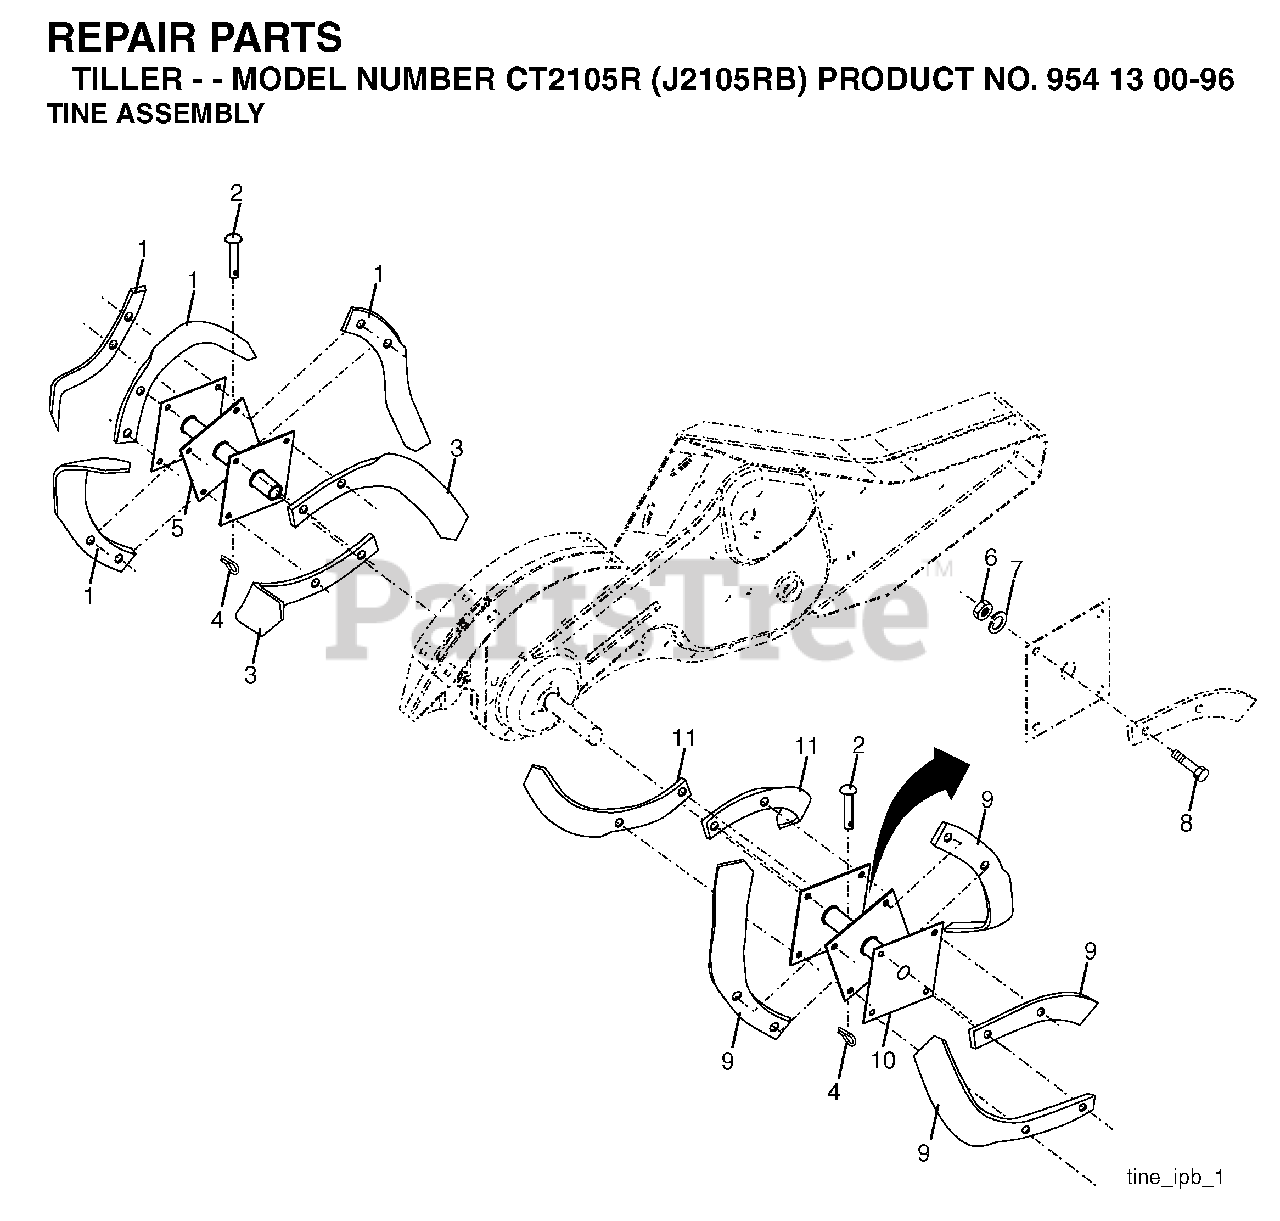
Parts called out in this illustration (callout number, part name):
1	TINE TI
2	CLEVIS PIN
3	TINE.LH.12"
4	SPRING RETAINER
5	HUB & PLATE ASM LH
6	NUT
7	WASHER, LOCK 3/8
8	BOLT.HEX.001X20.37-24X1.ZINC
9	TINE TI
10	HUB & PLATE ASM RH
11	TINE.RH.12"(72R)
